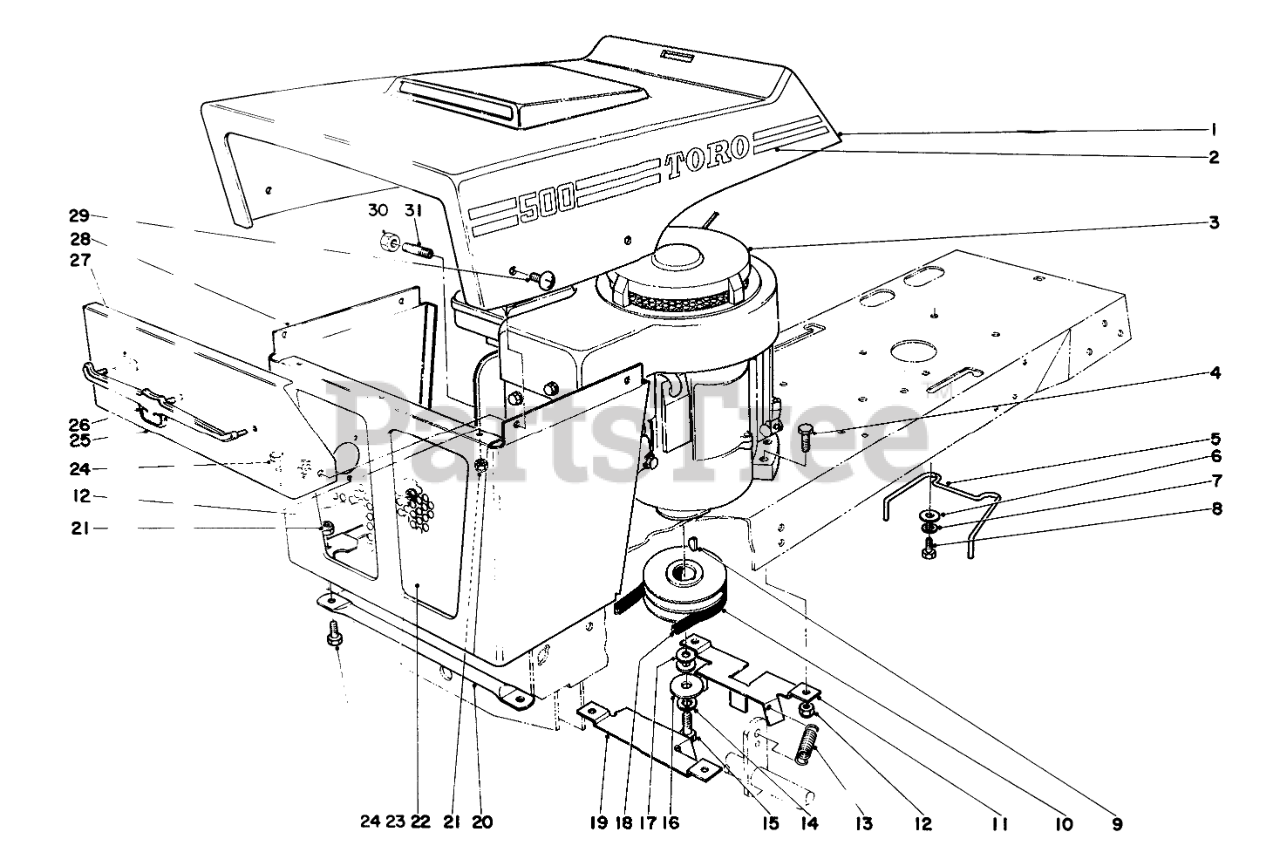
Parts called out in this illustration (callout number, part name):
2	Decal Hood Model 57043
3	Engine Model 57043
4	SCREW-HH
5	Belt Retainer
6	WASHER-PLAIN
7	WASHER-LOCK/SP
8	SCREW-HH
9	KEY-WOODRUFF
10	Engine Pulley
11	Belt Guide
12	NUT-LOCK, CONE
13	Spring Tension
14	WASHER-LOCK
15	SCREW-HH
16	Washer
17	WASHER-FLAT
18	ENGINE BELT
19	Belt Guide
20	Rod Grille Mount
21	NUT-LOCK, CONE
22	Grille Panel
23	NUT-LOCK, SIDE
24	SCREW-HH
25	Panel Grille
26	Bullshead
27	Timmerman Nut
28	Grille
29	Round Head Screw
30	Cap-Pipe
31	NIPPLE 3/8NPTX 1.50
